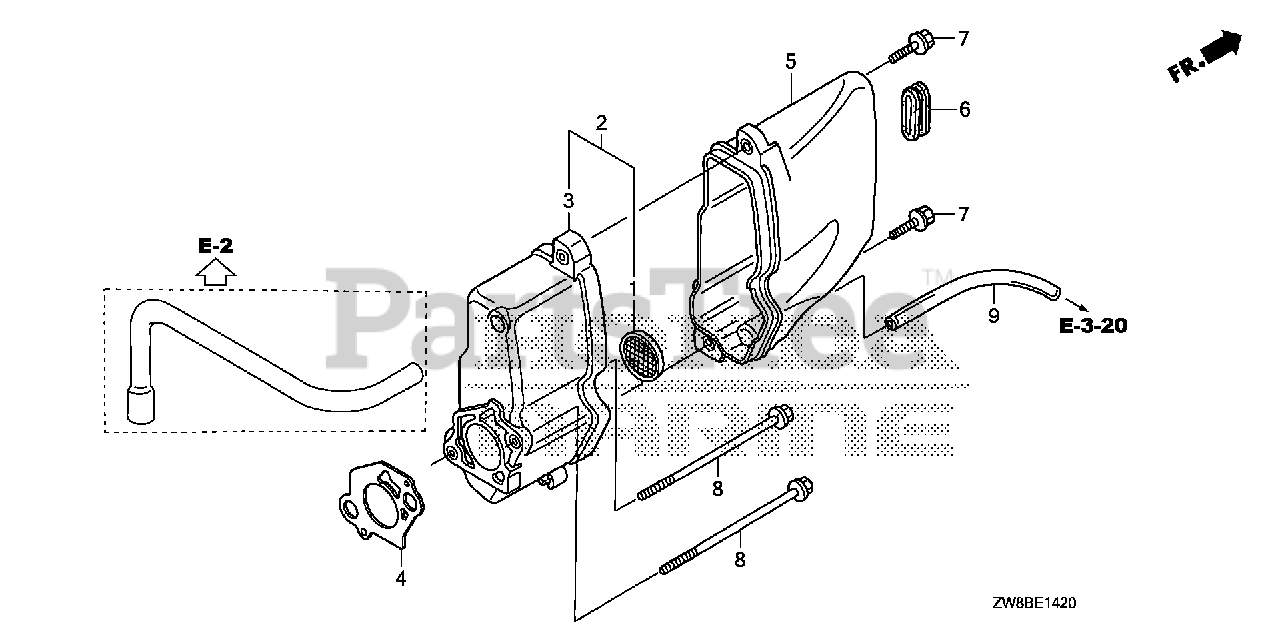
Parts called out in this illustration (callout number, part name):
1	TRAP, FLAME
2	PLATE ASSY., MUFFLER
3	PLATE, MUFFLER
4	GASKET, MUFFLER PLATE
5	COVER, MUFFLER
6	RUBBER A, TANK MOUNTING
7	BOLT, FLANGE (6X22)
8	BOLT, FLANGE (6X98)
9	TUBE, VINYL (3.5X6.5X95)
